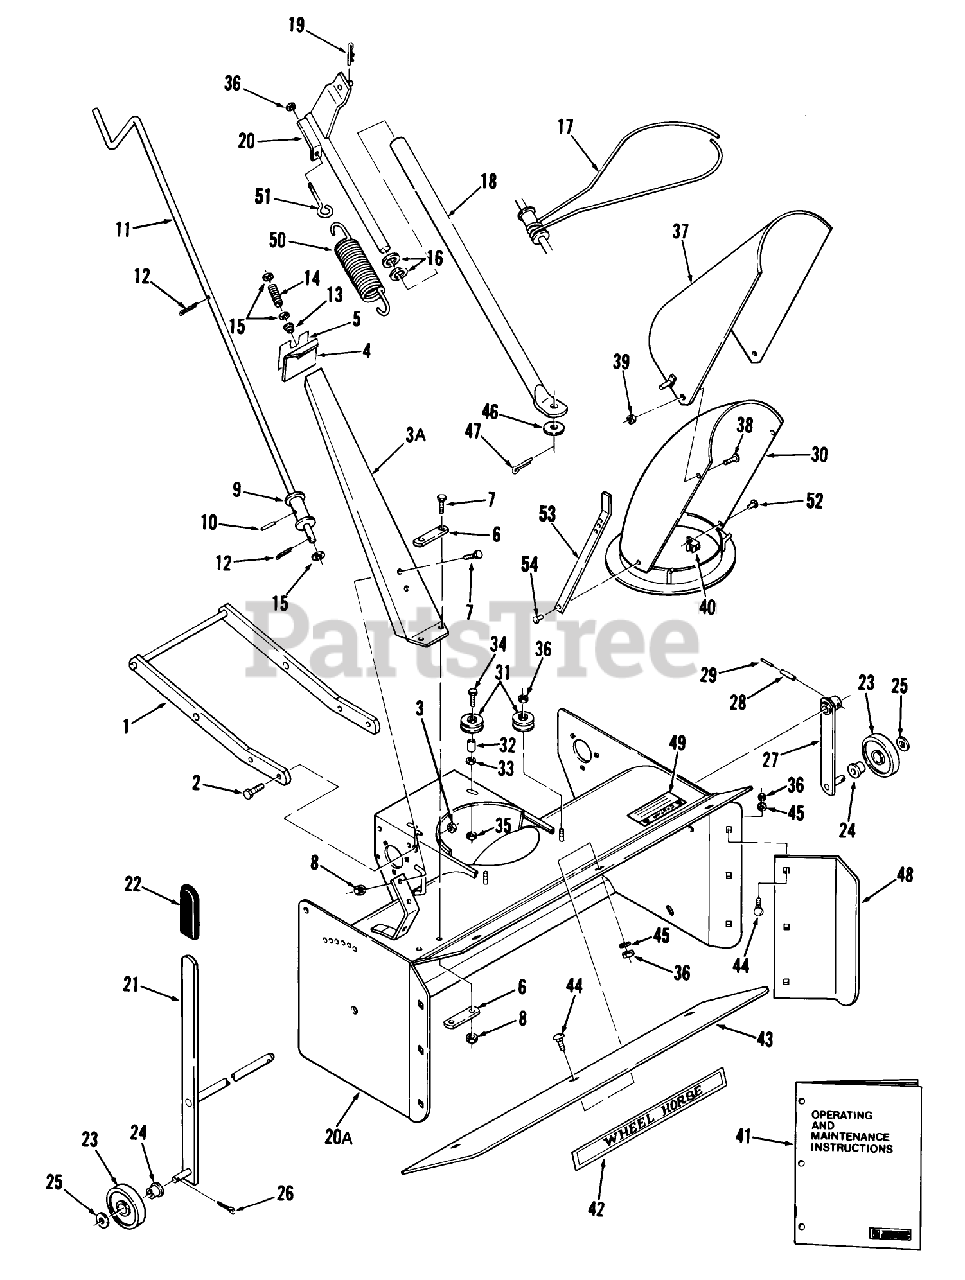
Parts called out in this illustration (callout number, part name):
9	ASSY TUBE CRANK *R
10	ROLL PIN 1/4 X 1-1/4
13	NYLINER BUSHING
14	SPRING-COMPRESSION
17	CABLE
19	Hairpin
22	GRIP
28	ROLL PIN 1/4 X 1-1/4
29	PIN-SPIROL
40	CLAMP
41	Operating and Maintenance Instructions
50	SPRING
51	EYEBOLT
52	RIVET-4
54	RIVET
